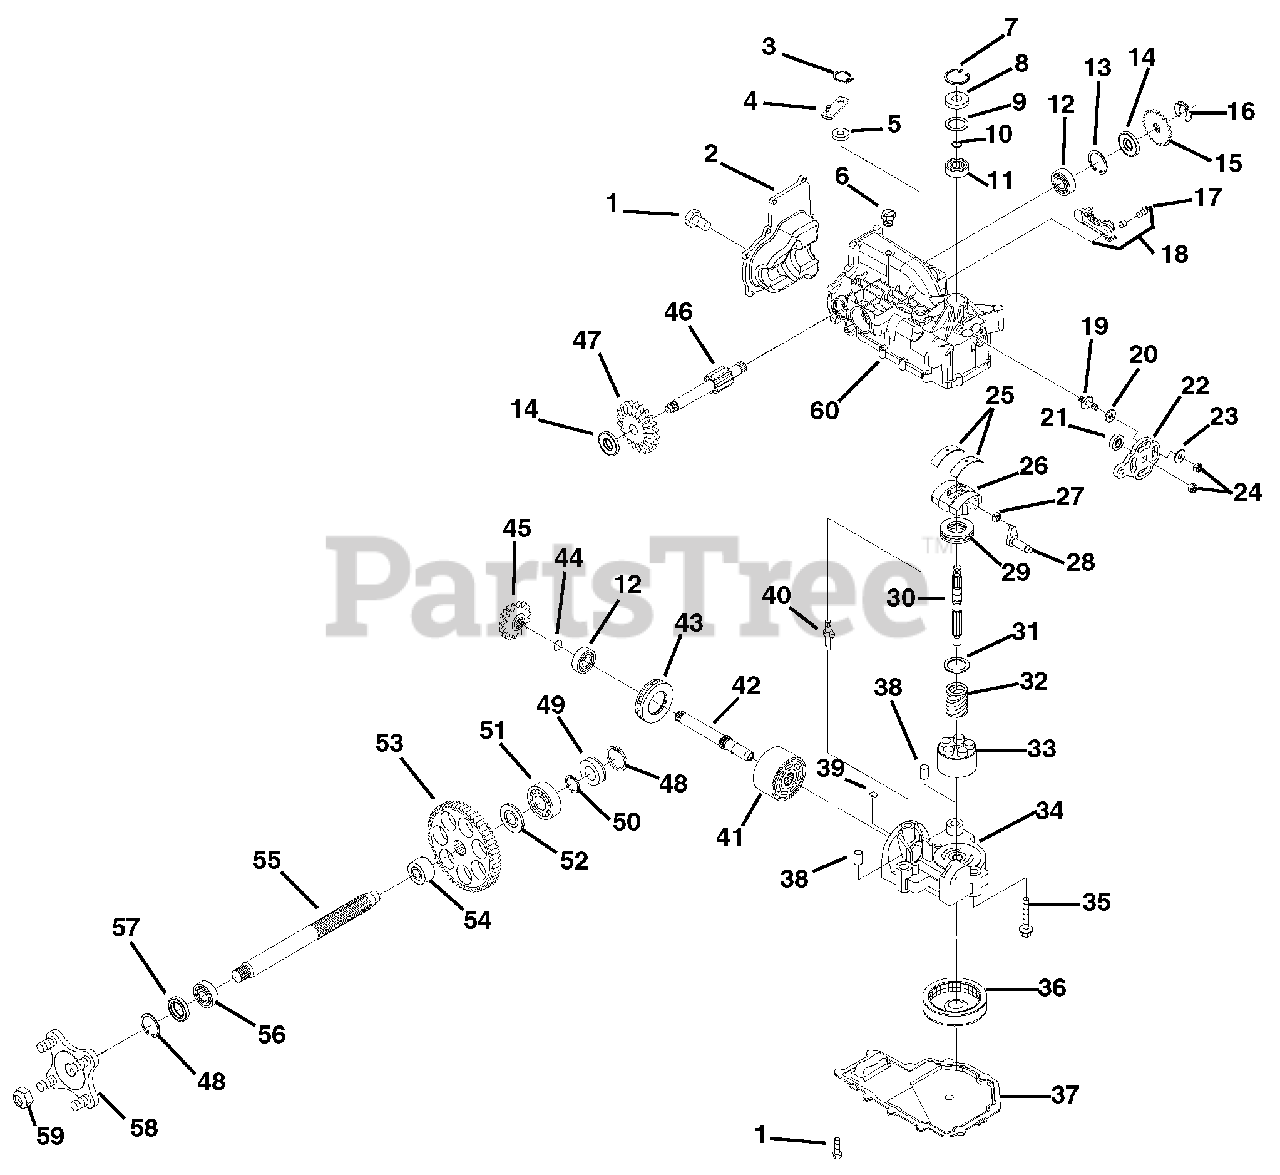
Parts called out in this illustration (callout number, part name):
1	Screw .25-20 x .75
2	Cover-Back
3	Ring-Retaining
4	Arm-Bypass
5	Seal-Lip
6	Plug-Plastic
7	Ring-Retaining
8	Seal-Lip
9	Spacer
10	Ring-Wire Retaining
11	Bearing-Ball
12	Bearing-Ball
13	Ring-Retaining
14	Seal-Brake Shaft
15	Brake Disc
16	Kit-Retaining Ring
17	Screw-Hex Washer Head 1/4-20 x 7/8
18	Service Assembly-Right Hand Brake Arm
19	Stud-Short 5/16-24
20	Friction Puck
21	Seal-Lip
22	Arm-Control
23	Washer
24	Nut
25	Cradle Bearing
26	Variable Swashplate
27	Slot Guide
28	Arm-Trunnion
29	Bearing-Thrust 30 x 52 x 13
30	Shaft-Input
31	Washer-Block Thrust
32	Spring-Block
33	Assembly-Cylinder Block 10cc
34	Assembly-Center Section
35	Screw
36	Filter
37	Housing-Lower
38	Pin-Alignment
39	Bypass Plate
40	Bypass Actuator
41	Assembly-Cylinder Block 21cc
42	Shaft-Motor
43	Bearing-Thrust 42 x 68 x 16
44	Ring-Wire Retaining
45	Gear-Bevel 14T
46	Kit-Brake Shaft
47	Gear-Bevel 19T
48	Ring-Retaining - Axle
49	Seal-Plug - Side
50	Ring-Retaining - Axle
51	Bearing-Ball 20 x 47 x 14
52	Bushing-Axle
53	Gear-Spur 53T
54	Bushing-Axle
55	Shaft-Axle
56	Bearing-Ball 25 x 47 x 12
57	Seal
58	Assembly-Hub
59	Nut-Hex 3/4-16
60	Housing-Upper Assembly
